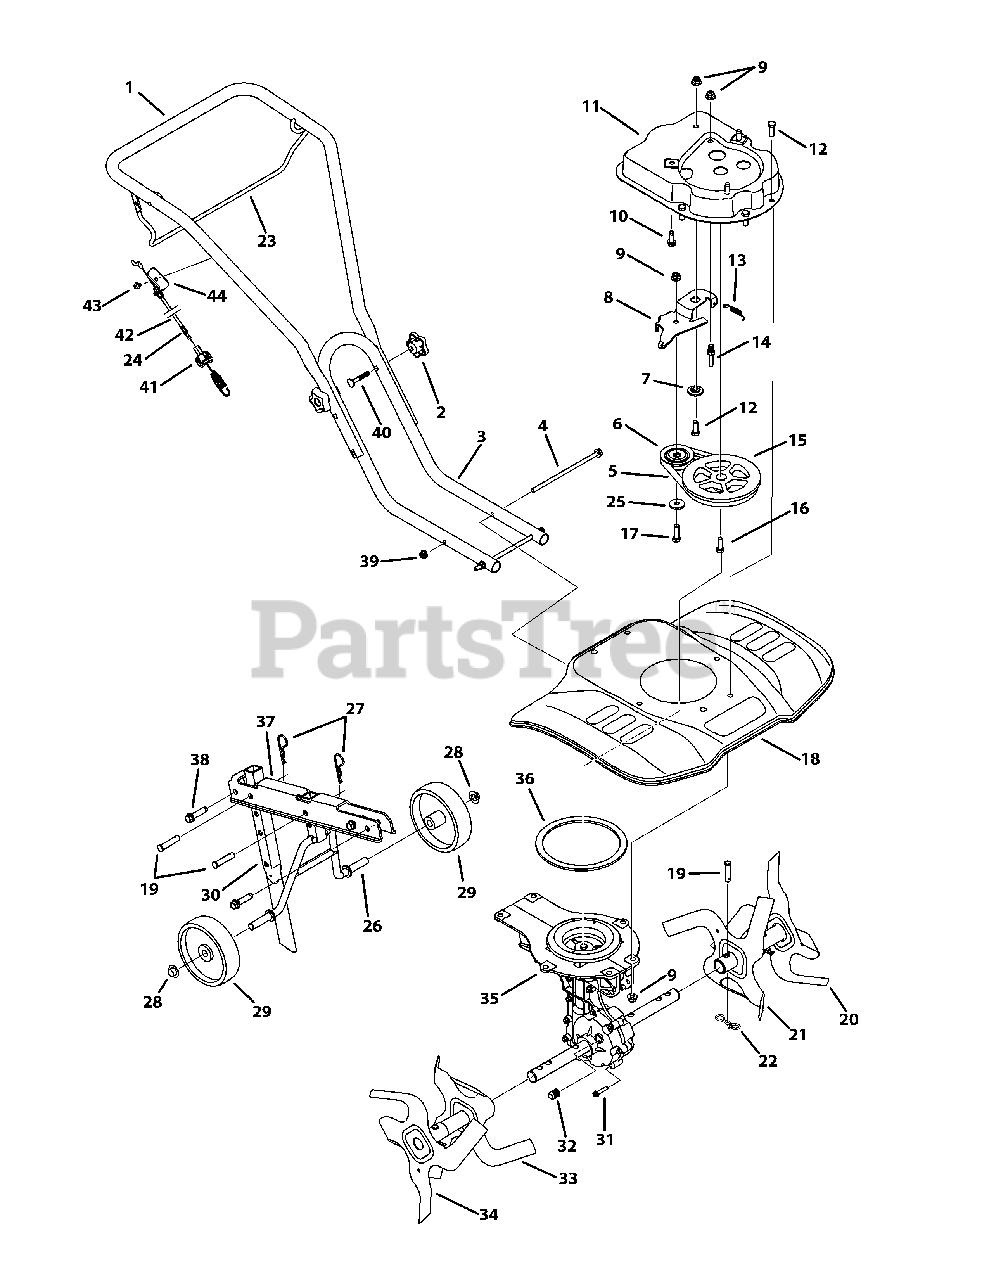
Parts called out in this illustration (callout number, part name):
1	Upper Handle
2	Star Handle Knob
3	Lower Handle
4	Flange Screw: 5/16-18:75:GR5
5	V-Belt
6	Idler Pulley
7	Shoulder Spacer
8	Idler Bracket
9	Flange Lock Nut: 3/8-16
10	TT Screw: 3/8-16:100
11	Belt Cover
12	Hex Cap Screw: 3/8-16:100
13	Extension Spring
14	Stud: 33 x 15: 3/8-16
15	Flywheel Pulley
16	Hex Cap Screw: 3/8-24:100
17	Hex Cap Screw: 3/8-16:155
18	Tine Shield 61 cm
19	Clevis Pin
20	Outer Tine Assembly LH
21	Inner Tine Assembly LH
22	Cotter Pin, Bow Tie
23	Clutch Bail
24	Retaining Ring
25	Flat Washer, 406 x 875 x 059
26	Rear Wheel Tube Assembly
27	Cotter Pin
28	Push Cap
29	Wheel 5 x 138
30	Depth Stake Tube
31	TT Screw: 1/4-20:125
32	Pipe Plug: 3/8 NPT
33	Inner Tine Assembly RH
34	Outer Tine Assembly RH
35	Case Assembly
36	Gasket
37	Wheel Bracket
38	TT Screw: 3/8-16:150
39	Flange Lock Nut: 5/16-18
40	Carriage Bolt
41	Clutch Cable Fitting
42	Clutch Cable
43	TT Screw: 1/4-20:50
44	Cable Mount Bracket
